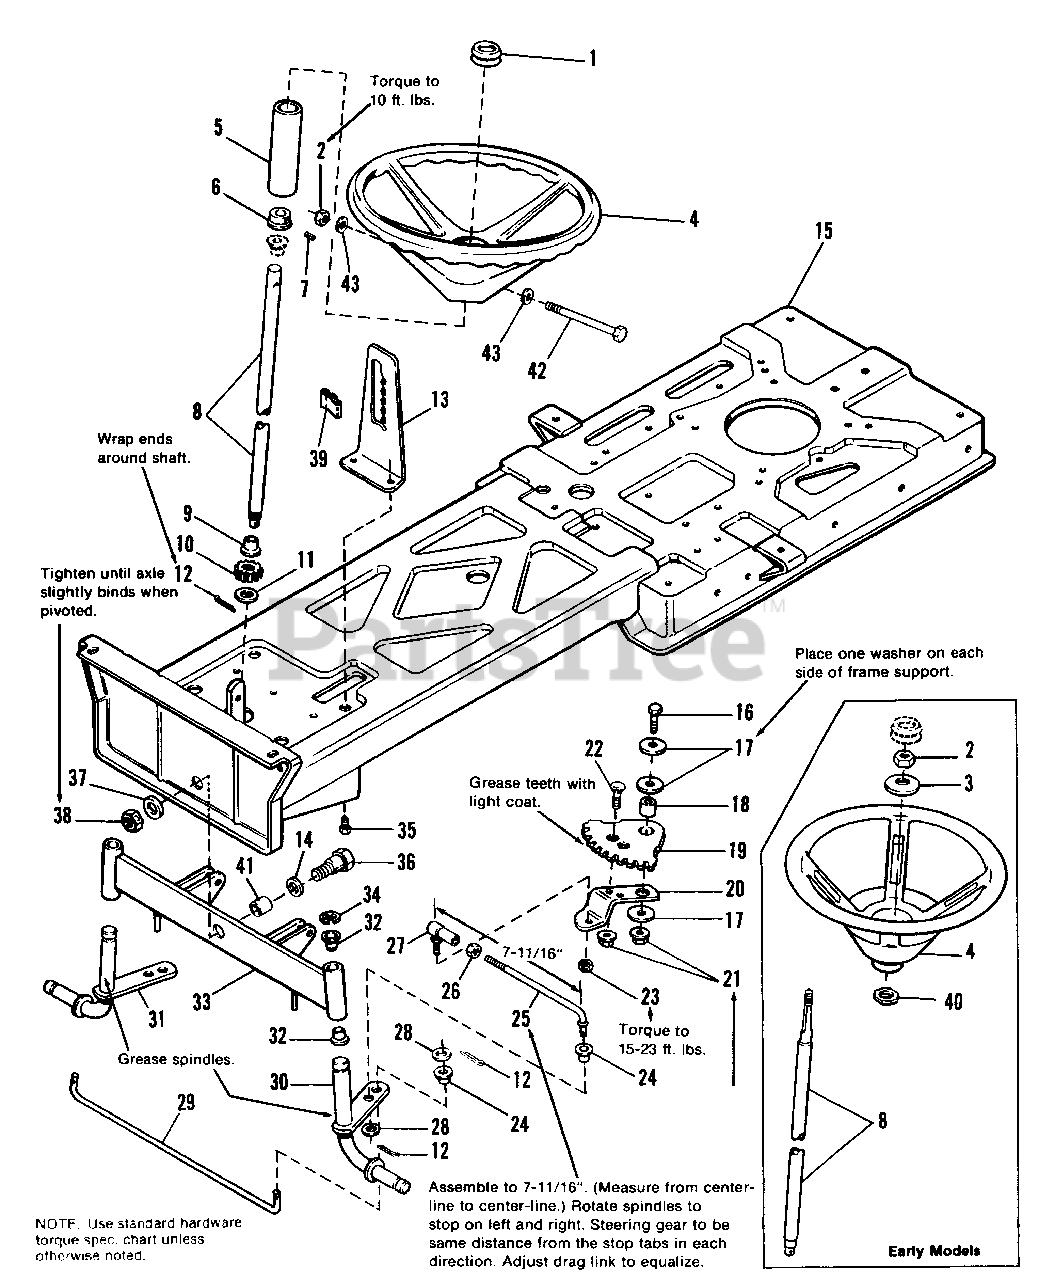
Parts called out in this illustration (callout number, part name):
1	CAP, Steering Wheel
2	LOCKNUT, Hex, Jam, 5/16-18
3	WASHER, Compression
4	STEERING WHEEL
5	TUBE, Steering
6	COLLAR, Set
7	SETSCREW, Plated, 5/16-18 x 5/16
8	SHAFT, Steering
9	BUSHING, Nylon
10	PINION, Steering
11	WASHER, Plain, 1/2
12	PIN, Cotter, 1/8 x 1
14	WASHER, Plain
15	FRAME ASSEMBLY
16	CAPSCREW, Hex, 13/16 x 2
17	WASHER, Plain, 13/32 x 1-1/2
19	GEAR, Steering
20	ARM, Steering Gear
21	LOCKNUT, Hex, Flange, 3/8-16
22	BOLT, Carriage, 3/8-16 x 7/8
23	LOCKNUT, Hex, 3/8-24
26	NUT, Hex, Jam, 3/8-24
28	WASHER, Plain, 3/8
30	SPINDLE ASSY., L.H.
31	SPINDLE ASSY., R.H.
32	BUSHING, Nylon
33	AXLE ASSY.
34	E-RING, Retaining (3/4 dia. shaft)
35	SCREW, Taptite, 5/16-18 x 1/2
36	CAPSCREW, Hex Hd., 1/2-20 x 1-1/2
37	WASHER, Spring
38	LOCKNUT, Hex, Jam, 1/2-20
40	WASHER, Hex
42	BOLT, Hex, 5/16-18 x 3-1/2
43	WASHER, 5/16
